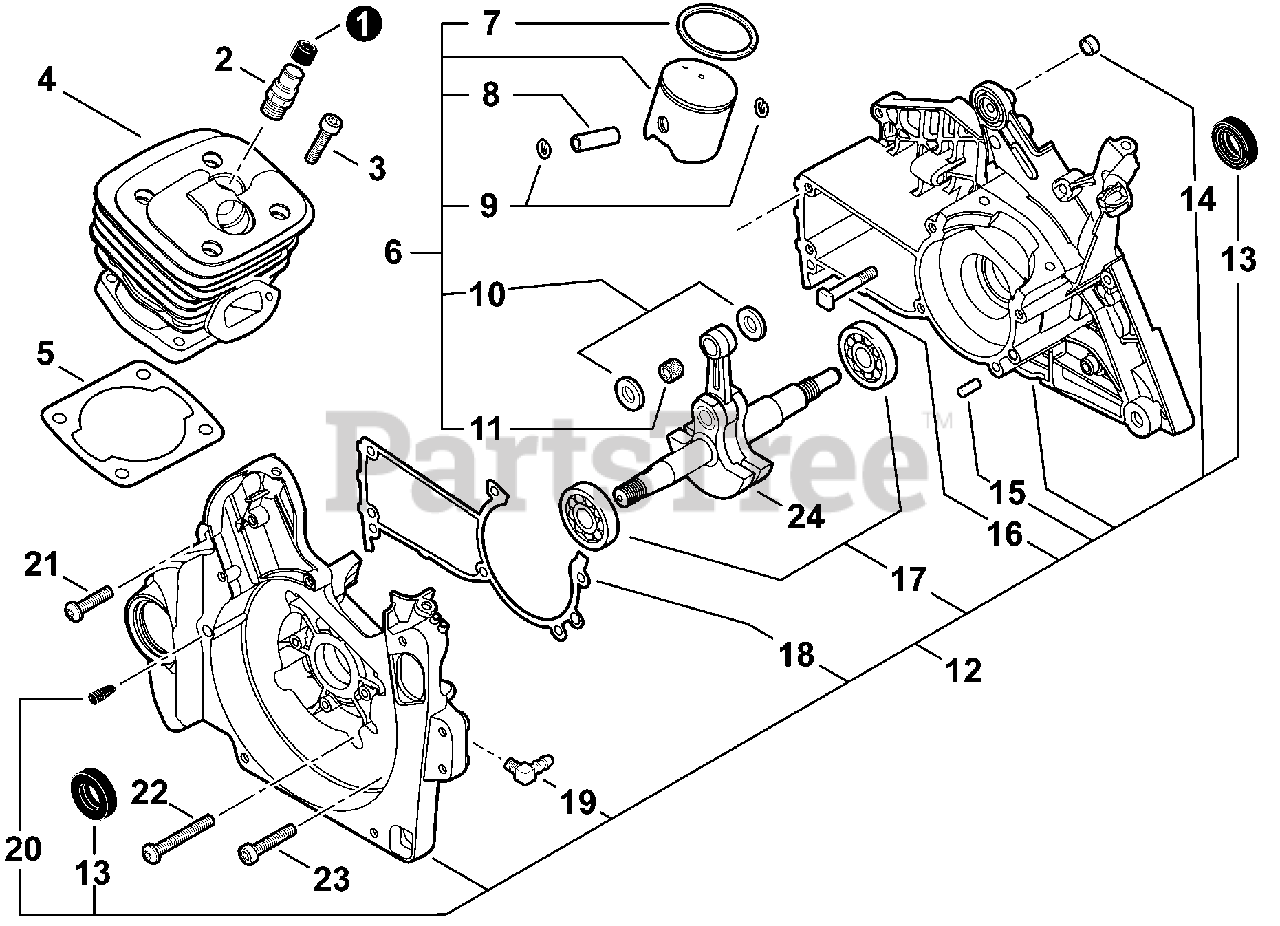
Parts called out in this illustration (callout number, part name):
1	COVER, DUST
2	VALVE ASSY, DECOMPRESSION
3	BOLT, TORX 5×25
4	CYLINDER
5	GASKET, CYLINDER
6	PISTON KIT
7	RING, PISTON
8	PIN, PISTON
9	RING, SNAP Ø11
10	WASHER, THRUST
11	BEARING, NEEDLE 11
12	CRANKCASE SET
13	SEAL, OIL 15
14	SPACER 12×10×T: 1.0
15	PIN, LOCATING 5×10
16	BOLT, STUD M8×1.25×34.5
17	BEARING, BALL 6202
18	GASKET, CRANKCASE
19	CONNECTOR, PIPE
20	VENT ASSY
21	BOLT, TORX 5×20
22	BOLT, TORX 5×35
23	BOLT, TORX 5×25
24	CRANKSHAFT ASSY
